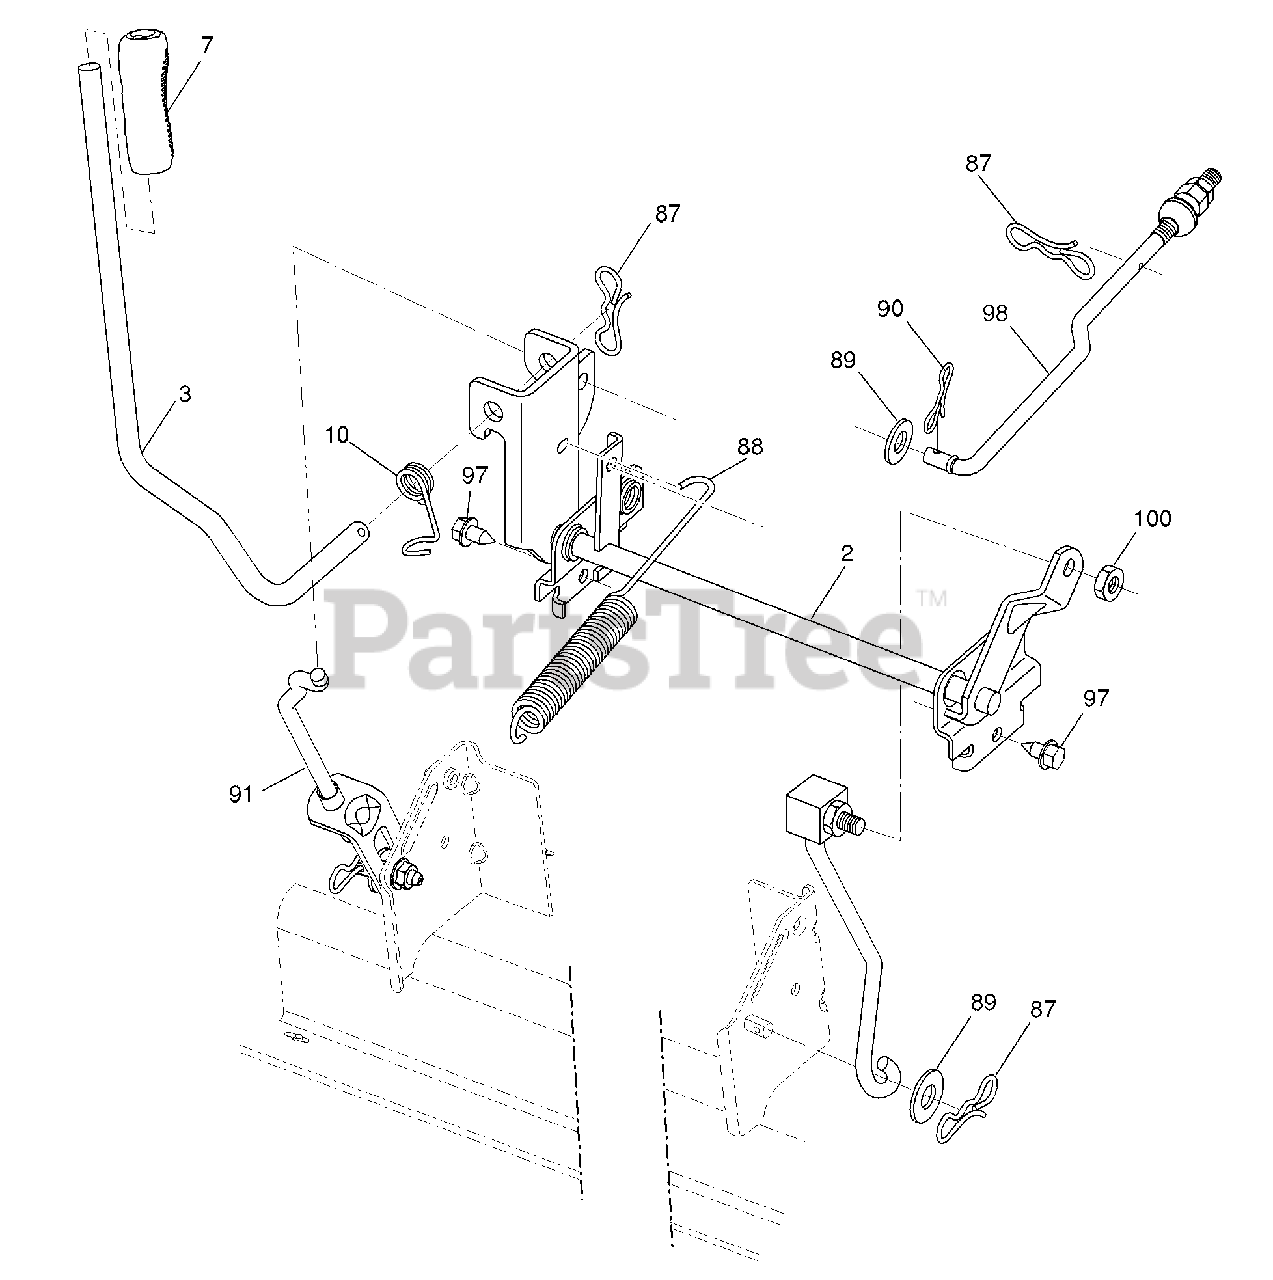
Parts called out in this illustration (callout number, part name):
2	Shaft Asm., Lift
3	Lever Asm., Lift Rh
7	Grip, Lever
10	Spring Torsion
87	Pin Cotter 7/16 Bow Tie Lock
88	Spring Lift Assist
89	Washer Clear Zinc
90	Pin Cotter 5/16 Bow Tie Lock
91	Link Lift Susp Mower Rear
97	Screw 3/8-16 x .75 Smgml Tap/R.Z
98	Link Lift Susp. Front Mower
100	Nut Center Lock 3/8-16 UNC
